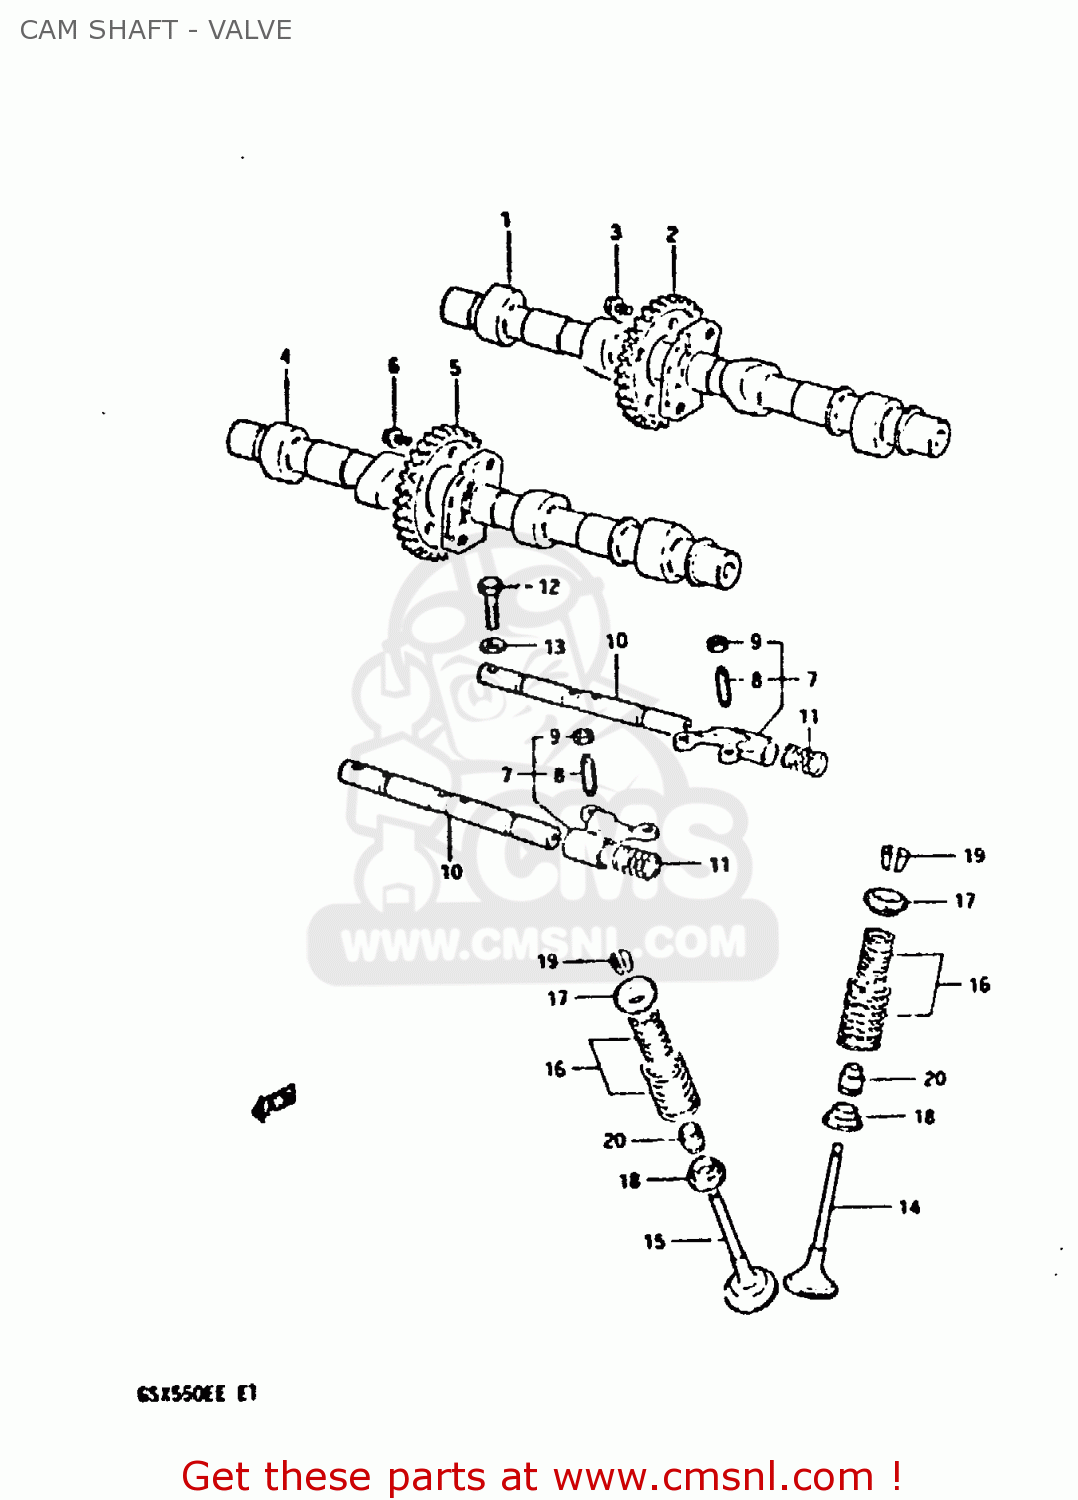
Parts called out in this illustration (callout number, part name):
1	CAMSHAFT,INTAKE
2	SPROCKET,INTAKE CAMSHAFT
3	BOLT(7X11)
4	CAMSHAFT,EXHAUST
5	SPROCKET,INTAKE CAMSHAFT
6	BOLT(7X11)
7	ARM,VALVE ROCKER
8	SCREW,TAPPET ADJUSTING
9	NUT,ADJUSTING
10	SHAFT,VALVE ROCKER
11	SPRING
12	BOLT
13	WASHER
14	VALVE,INTAKE
15	VALVE,EXHAUST
16	SPRING SET,VALVE
17	RETAINER,VALVE SPRING
18	SEAT,VALVE SPRING
19	COTTER,VALVE
20	SEAL,OIL(5X10.5X8.4)
